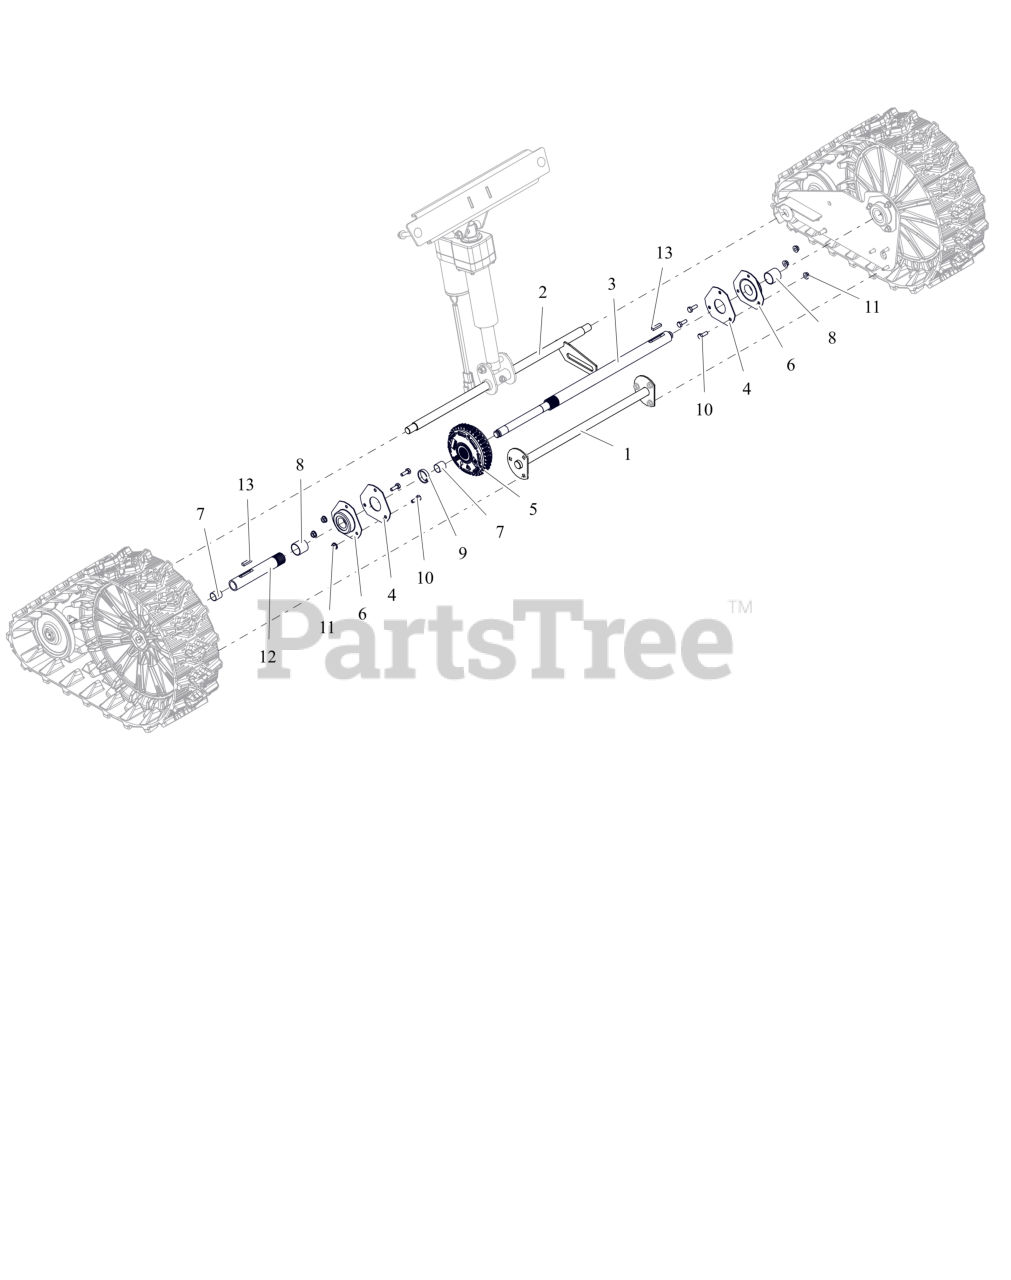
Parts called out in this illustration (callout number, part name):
1	SUPPORT, FRONT-BWT
2	AXLE- REAR - BWT WLDMT ELEC
3	AXLE, LONG-TRACK DIFFERENTIAL
4	PLATE, BEARING SPACER
5	DIFFERENTIAL, AUTOMATIC
6	BRG-FLG 1.003/1.000 3 BOLT
7	BSHG-SLV .706X.764X.75 BRZ
8	BSHG-SLV, 1.012X1.125X1.00
9	BSHG, SLV 1.062X1.228X.268
10	BLT, HEX .25-20X.75 G5 ZCC
11	NUT-LK-CTR-FLG .25-20 ZC120
12	AXLE, SHORT-W/BUSHINGS
13	KEY-RECT .25X.188X1.00
